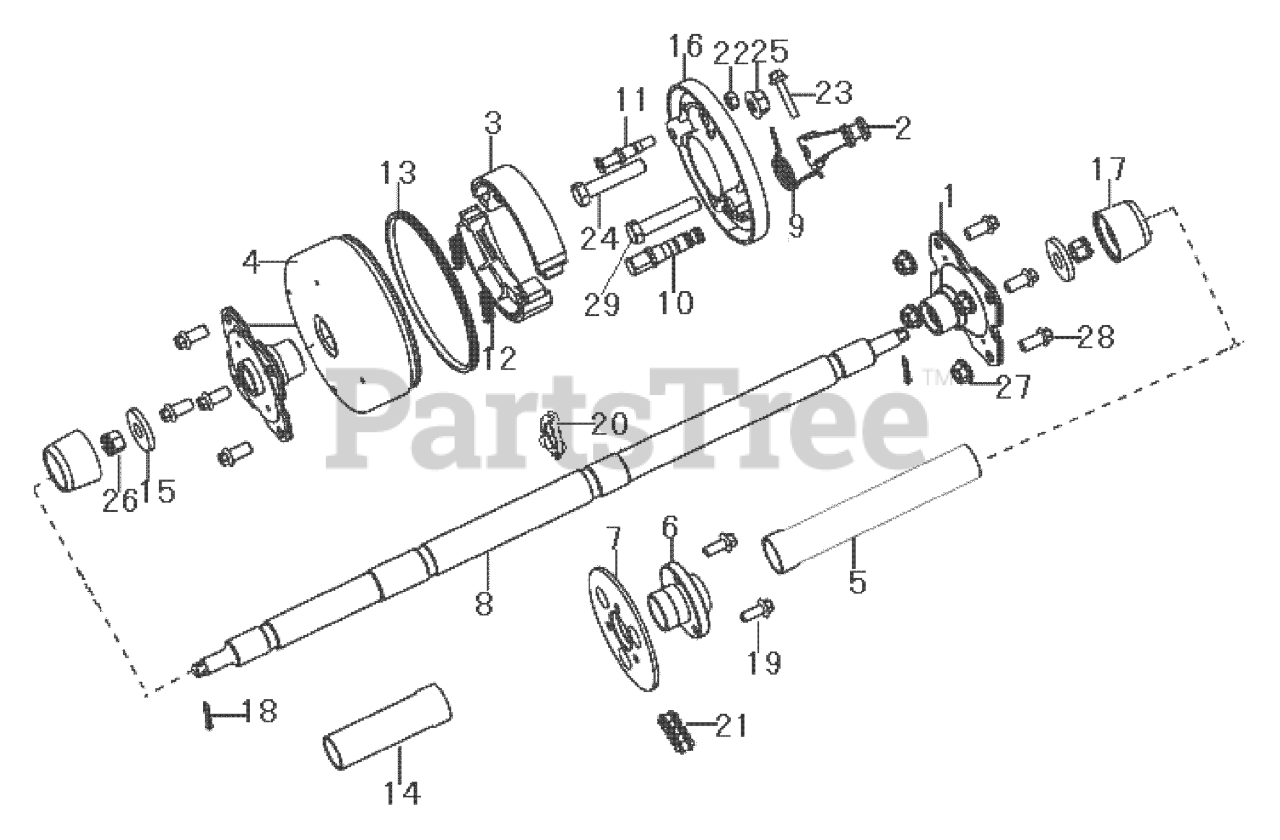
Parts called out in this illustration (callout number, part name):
1	HUB, REAR WHEEL MOUNTING
2	BRAKE ARM, REAR
3	BRAKE SHOE ASSY.
4	BRAKE DRUM
5	SPACER, AXLE
6	HUB, SPROCKET MOUNTING
7	SPROCKET
8	AXLE, REAR
9	SPRING, TORSION
10	CAMSHAFT, BRAKE
11	PIN, PIVOT
12	SPRING, RETURN
14	SLEEVE, AXLE
16	PLATE, BACKING
17	HUB CAP
18	PIN, COTTER
20	LOCKING RING, BOLT
22	LOCK NUT
26	NUT, CASTLE
